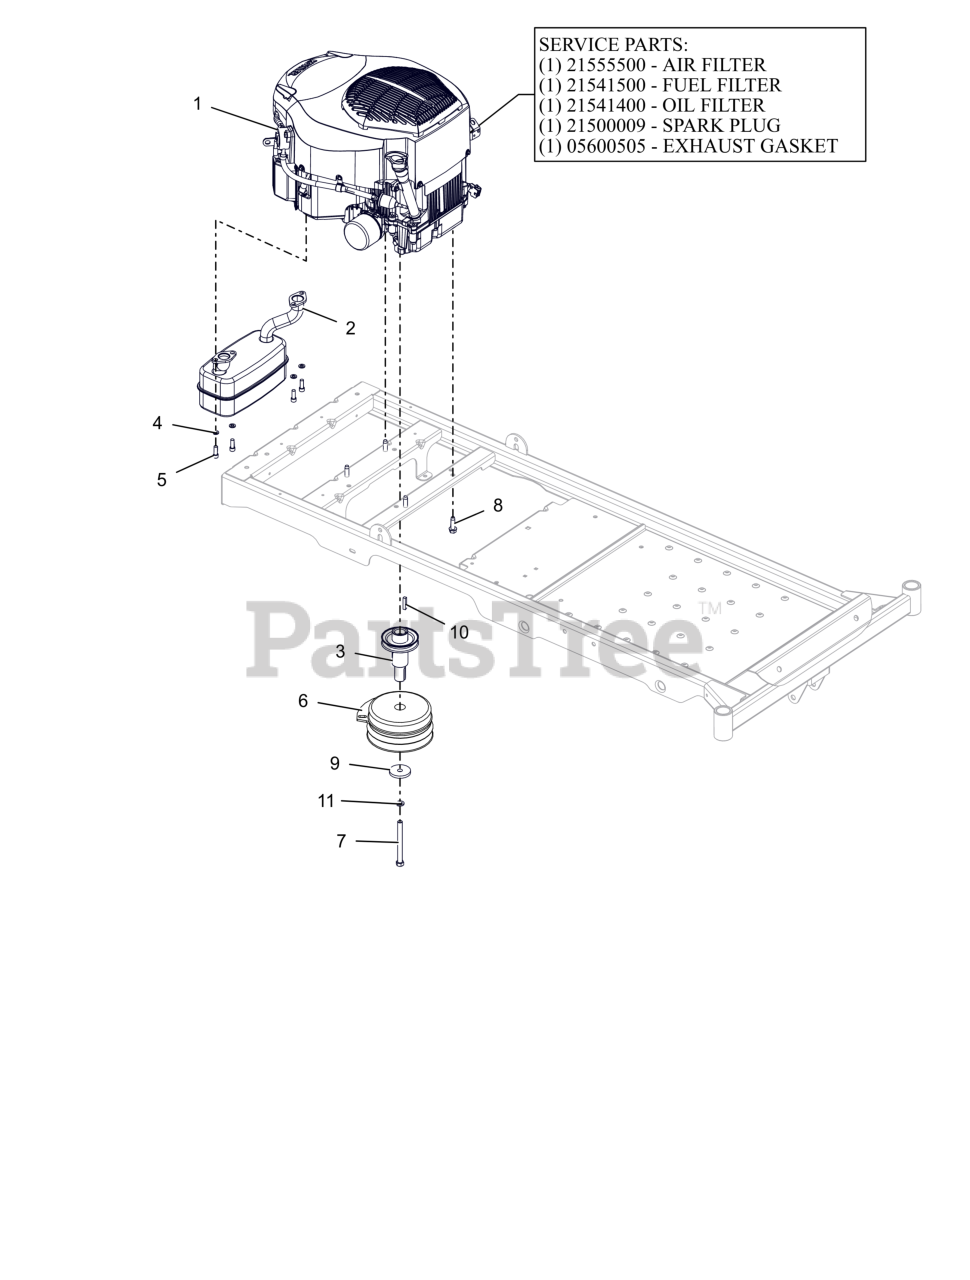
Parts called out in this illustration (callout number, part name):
1	ENGINE, KOHLER TWIN 19 HP
1	AIR CLEANER, KOHLER
1	FILTER, FUEL
1	FILTER, ENGINE OIL (COURAGE)
1	PLUG, SPARK KOHLER
1	GASKET, MUFFLER COURAGE TWIN
2	MUFFLER, KOHLER TWIN
3	WLDMT, CRANKSHAFT EXTENSION
4	WSHR,LK-REG .312X.078 ZCC
5	SCR-CAP .31-18X.88 S/HD G8 ZCC
6	CLUTCH, 105 FT*LB MONO POLE
7	BLT, HEX .44-20X4.50 G8 ZCC NT
8	SCR,TAP .375-16X1.25HWH TR ZCC
9	WSHR, FLT .469X2.00X.250 ZCC
10	KEY-SQ .25 X 1.25 X .25 SAE
11	WSHR, LK-REG .438X.109 ZCC
